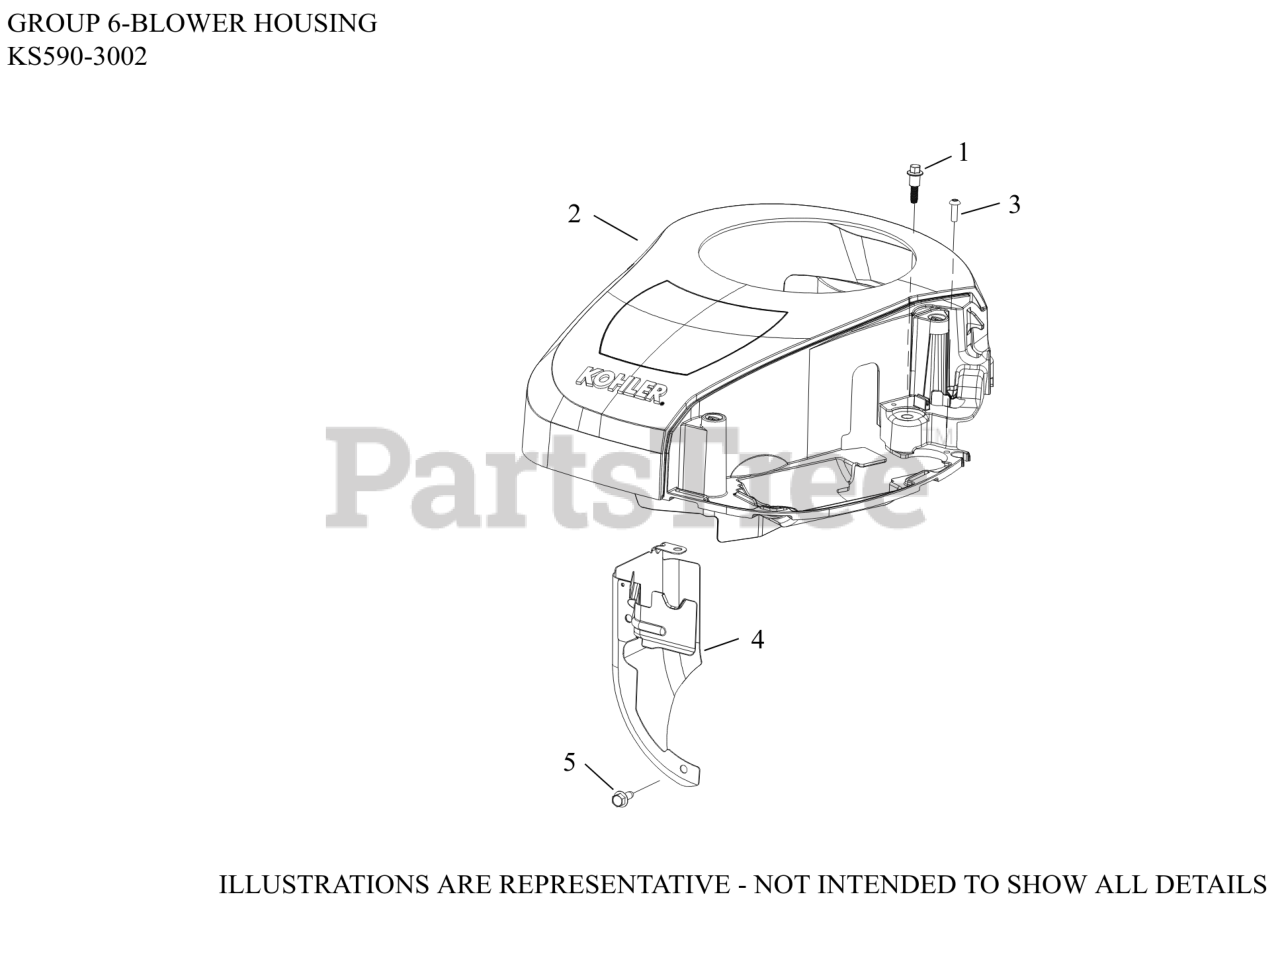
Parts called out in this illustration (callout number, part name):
1	SCREW, SHD THD FRM M6X1X26
2	KIT, BLOWER HOUSING
3	SCREW, HI-LOW
4	BAFFLE, BARREL ASSY
5	SCREW, THREAD FORMING
